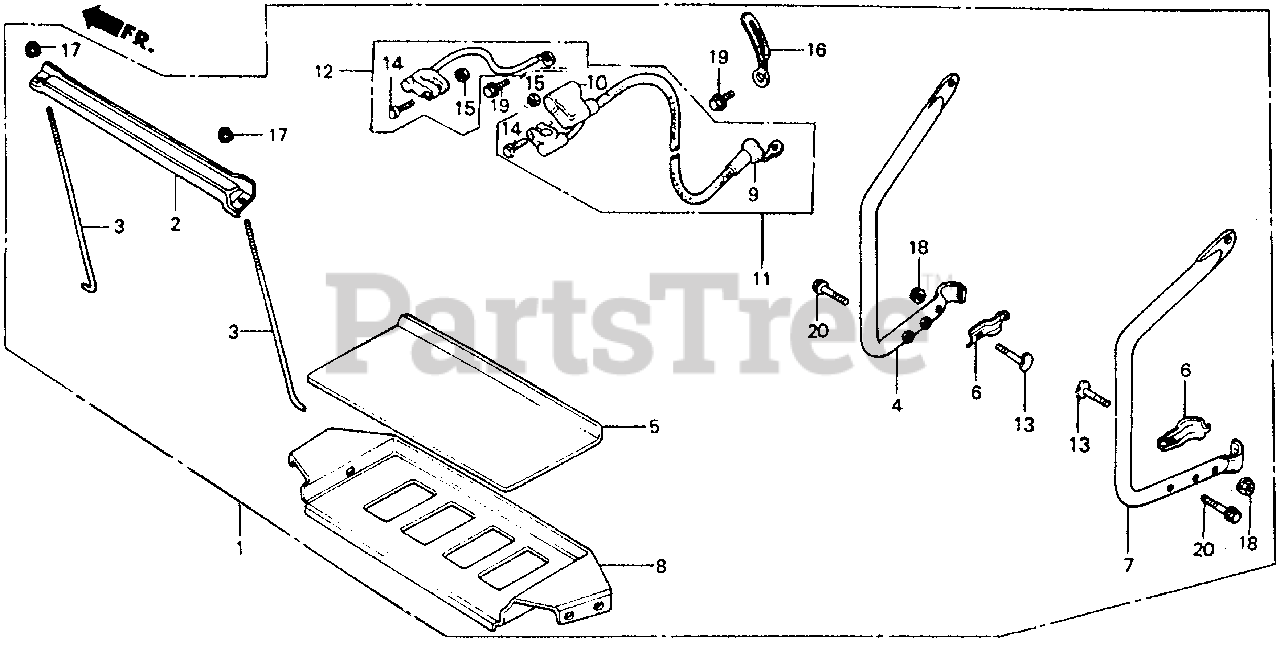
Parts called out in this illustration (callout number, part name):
1	TRAY KIT, BATTERY
2	PLATE, BATTERY SETTING
3	BOLT, BATTERY SETTING (220MM)
4	GUARD, FR. BATTERY
5	PLATE, BATTERY
6	PLATE, GUARD PIPE
7	GUARD, RR. BATTERY
8	BASE, BATTERY TRAY
9	COVER, TERMINAL
10	COVER, BATTERY PLUS TERMINAL
11	CABLE ASSY., STARTING
12	CABLE ASSY., GROUND
13	BOLT, HANDLE HOLDER
14	BOLT (6X32)
16	CLIP, HEAD
17	NUT, FLANGE (6MM)
18	NUT, FLANGE (8MM)
19	BOLT, FLANGE (6X12)
20	BOLT, FLANGE (6X28)
